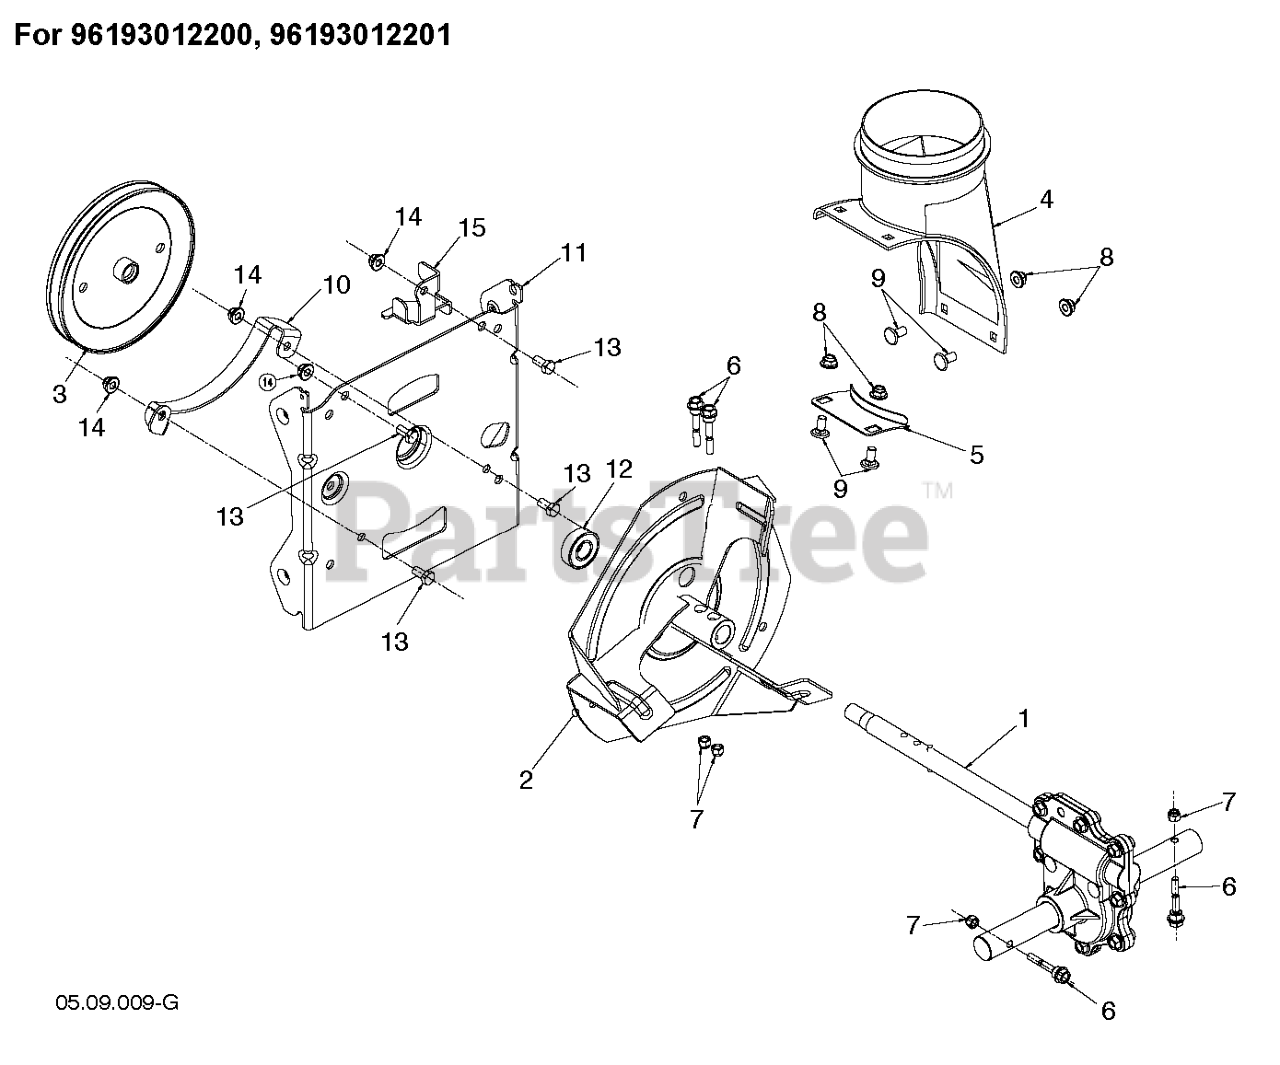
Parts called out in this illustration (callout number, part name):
1	GEAR BOX ASM ALUM
2	IMPELLER.STEEL.SNOW.BLACK
3	PULLEY SCREW ON 7.3 5/8
4	CHUTE.DISCHARGE.BASE
5	BRACKET, CORNER DISCHARGE
6	BOLT.1/4-20 X 1-13/16 SHEAR
7	LOCKNUT.NYLOC.1/4-20
8	NUT HEX FLG NYLOCK BLK 5_16-1
9	BOLT CARR WAFER BLK 5_16-18 X
10	BRACKET.BELT.KEEPER.LOWER.BLAC
11	BRACKET.AUG.HOUSING.INTER.BLAC
13	BOLT, HEX HEAD 5/16-18
14	NUTNYLOK.FLRANGE.5/16-18
15	GUIDE.LOWER.AUGER.BELT.479
